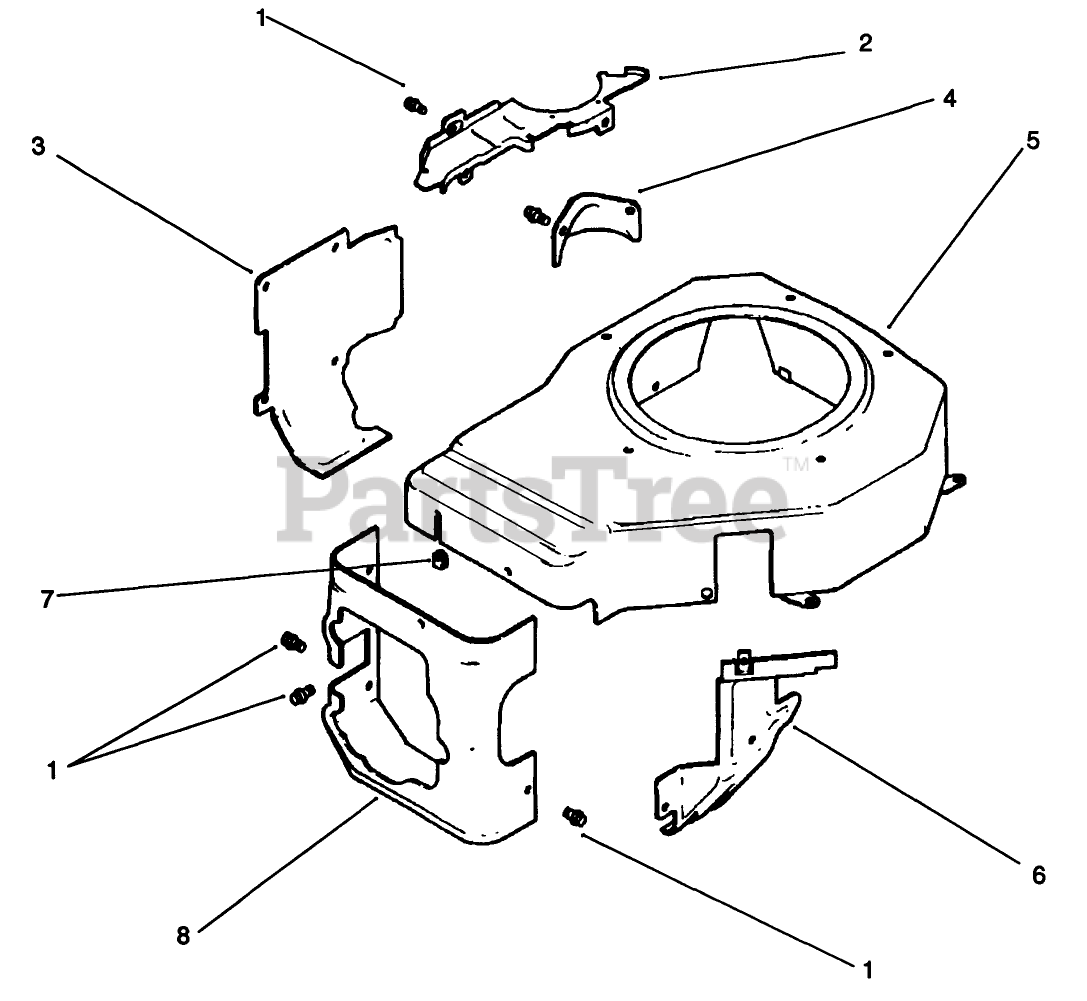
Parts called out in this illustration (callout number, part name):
2	Plate-Blower Housing (Only On: 72042,72043,72062,72063)
3	Baffle-Cylinder Barrel (Only On: 72042, 72063, 72062, 72043)
4	Cover-Starter
5	Cover-Housing
6	Baffle-Carburetor (Only On: 72042, 72043, 72062, 72063)
7	Grommet-Blower Housing (Only On: 72042, 72043, 72062, 72063)
8	Baffle-Cylinder Head
